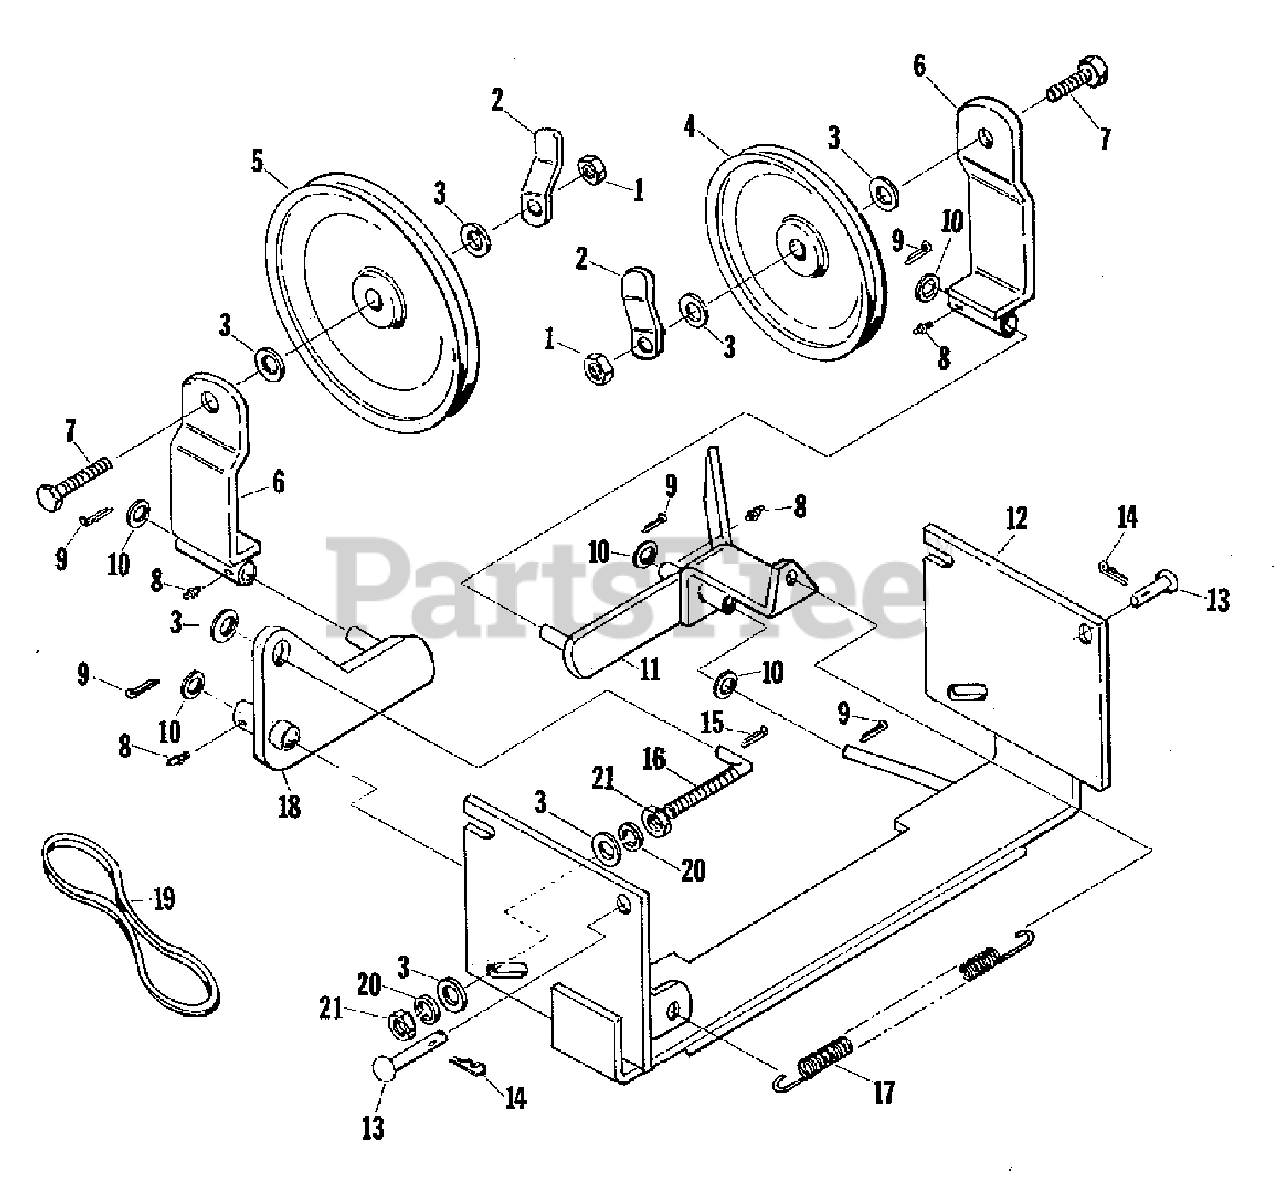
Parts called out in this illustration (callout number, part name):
1	NUT, Hex, Lock, 3/8-16
2	RETAINER, Belt
3	WASHER, Flat, 13/32 x 7/8
4	PULLEY, Idler "V"
5	PULLEY, Idler, Flat
6	BRACKET ASSEMBLY, Idler
7	SCREW, Hex Cap, 3/8-16 x 1-1/4
8	FITTING, Lube, Drive Type
9	PIN, Cotter, 1/8 x 1
10	WASHER, Special
11	PIVOT ASSEMBLY, Idler
12	HITCH ASSEMBLY
13	PIN, Round Head, 3/8 x 1-1/2
15	PIN, Cotter, 3/32 x 3/4
16	ROD, Adjusting
17	SPRING, P.T.O.
18	SUPPORT ASSEMBLY, Idler
20	WASHER, Lock, 3/8"
21	NUT, Hex, Jam
